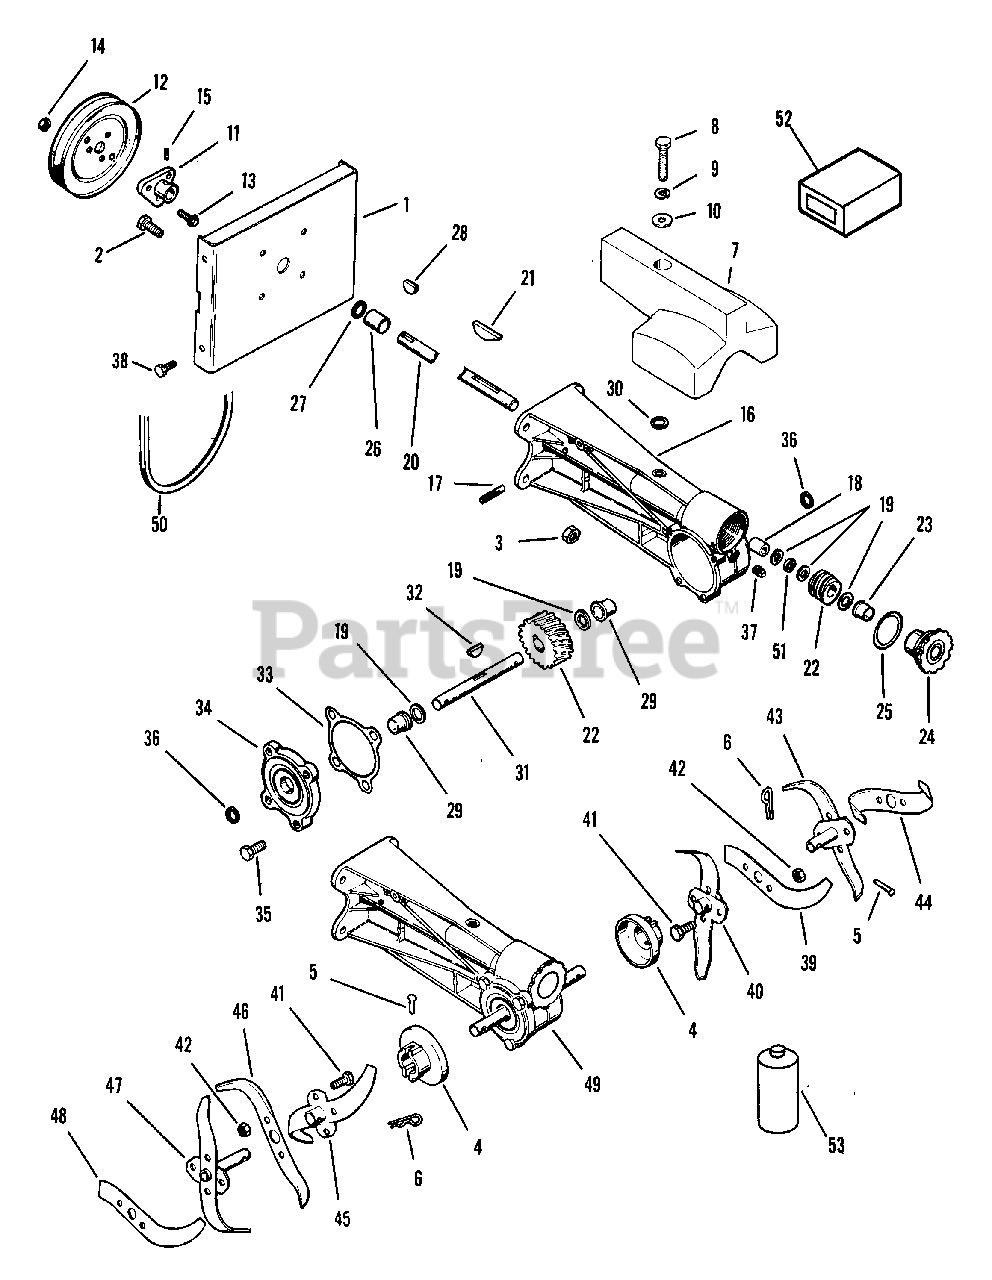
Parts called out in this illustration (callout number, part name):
1	TILLER MOUNTING PLATE
2	SCREW - FLG WIZ LOCK HH PL
3	NUT-LK-FLG .375-16 PL
4	DUST CAP
5	PIN, CLEVIS .243/.248X1.50 YWZ
6	PIN-HAIR INT .08X.18X1.18
7	TILLER WEIGHT
8	BLT-HEX .38-16X2.25 GR2
9	WSHR-LK .375X.094 MED PL
10	WSHR-FL-STL.406X.812X.065PL
11	HUB
12	PLY-V 7.0 X 1.25 3BLT
13	BLT-SERRDHD SL .31-18X.75 YZ
14	NUT-FLG. .312-18 PL
15	SCR-SET .32-18X.38 SKHCUPNL OH
16	GEARCASE
17	BREATHER
18	BSHG-SLV .750X1.000X.750
19	WSHR-HDND-THRST .755X1.40X.062
20	WORM SHAFT
21	KEY-FTHR .188X1.38X.188
22	WORM & WORM GEAR ASSEMBLY
23	BSHG-FLG .750X1.000X.750X1.132
24	ADJUSTMENT PLUG
26	BSHG-SLV .750X1.000X1.000
27	SEAL .750X1.000X.125
28	KEY-WDRF .188X.875X.375 SAE11
29	BSHG-FLG .750X1.250X.750X1.375
30	SHIM SPACER
31	TINE SHAFT
32	KEY-WDRF .188X.625X.25 SAE 61
35	BLT-SERHFWH .31-18X.75 PL
36	SEAL .750X1.980X.375
37	PIPE PLUG
38	BLT-SERHFWH .31-18X.50 PL
39	L H INSIDE TINE
40	L H INNER TINE SPOOL
41	BLT-HEX .31-18X.75 PL GR2
42	NUT-LK .312-18 GR A PL
43	L H OUTER TINE SPOOL
44	R H OUTSIDE TINE
45	R H INNER TINE SPOOL
46	R H INSIDE TINE
47	R H OUTER TINE SPOOL
48	L H OUTSIDE TINE
49	TILLER GEARCASE - ALUMINUM
50	V-BELT, 4L-COGGED
51	BRG-N THRST .754X1.24X.078
52	AIR CLEANER KIT
53	ARIENS 16 OZ.BOTTLE OF L2 LUBE
